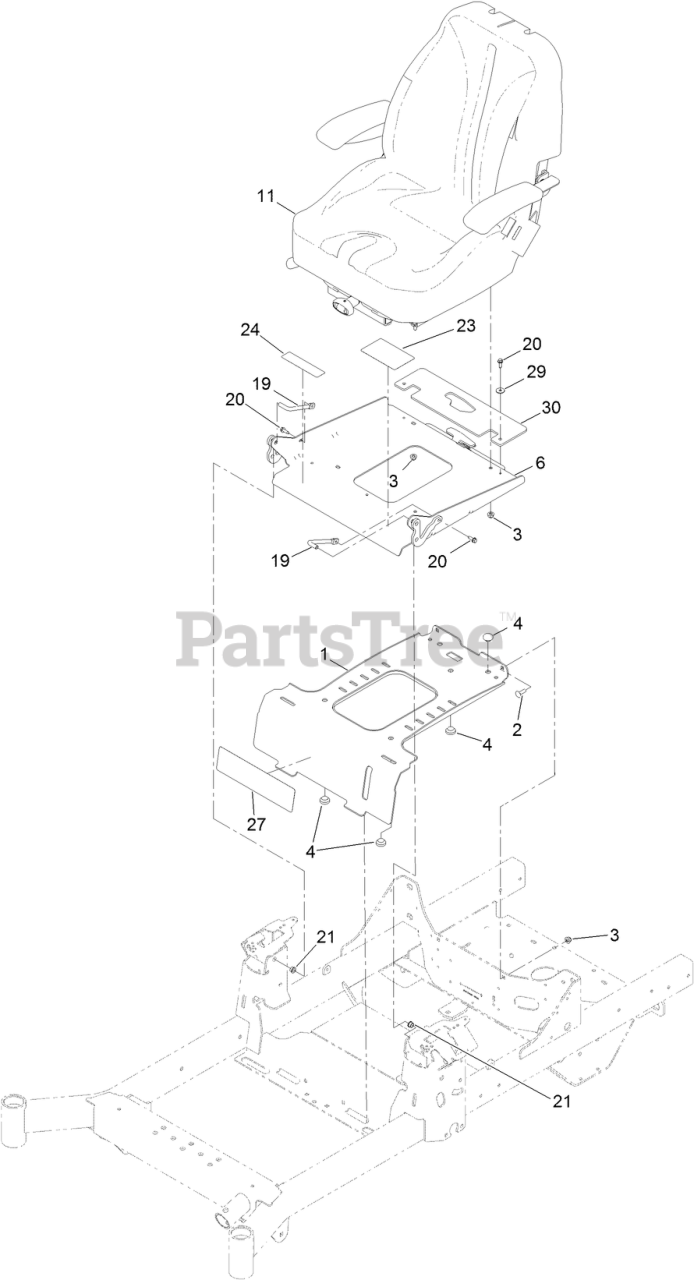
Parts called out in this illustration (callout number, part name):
1	PLATE-RETAINER, TANK
2	SCREW-CARR
3	NUT-HF, NI
4	BUMPER-SEAT
6	SEAT PAN AND LATCH ASM
11	SEAT ASM
19	PIN-PIVOT, SEAT
20	SCREW-HWH, THREAD ROLL
21	BUSHING-FLANGED
23	DECAL-AID, SERVICE
24	DECAL-LATCH, SEAT
27	DECAL-Z MASTER
29	WASHER
30	GUARD-SEAT, RUBBER
